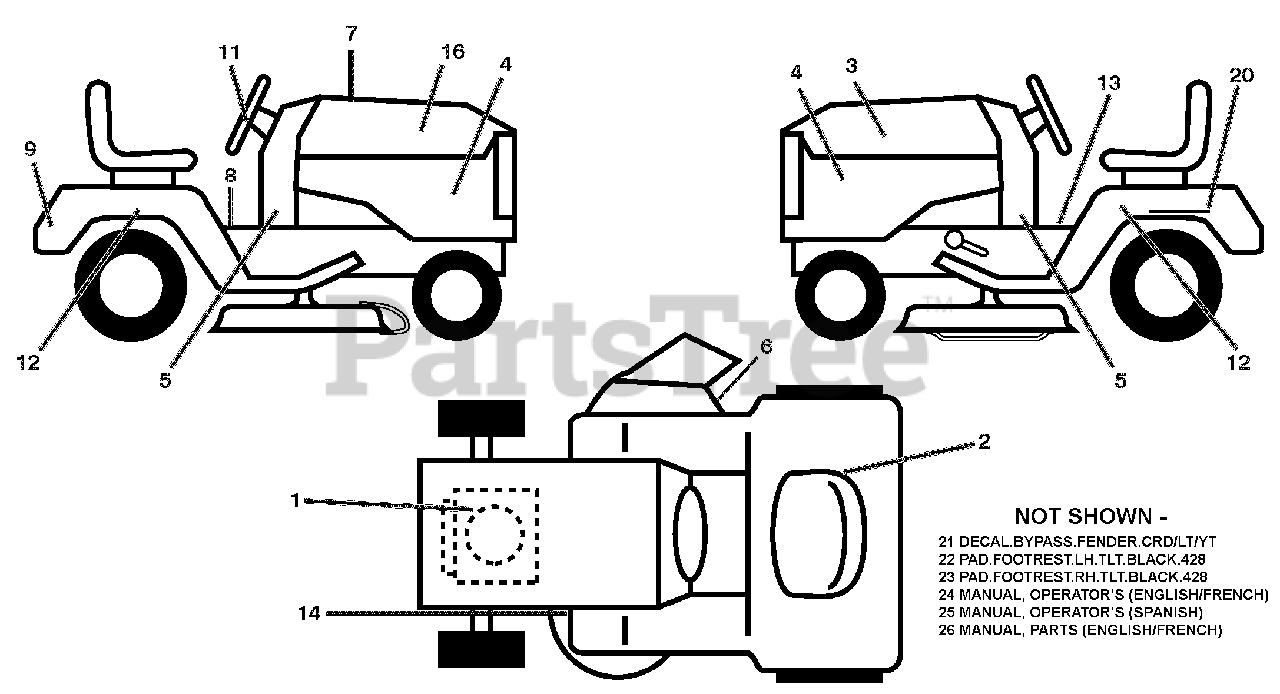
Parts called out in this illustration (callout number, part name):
1	DECAL ENGINE H.P.
2	Decal Fender Service
3	DECAL.HOOD.LH.3HIGH.ARIENS
4	Decal, Side Panel
5	DECAL.DASH.LWR.18HP.ARIENS
6	DECAL.MOWER.WARN.KEEP HAND AWY
7	DECAL.RPL.KH(SNGL).TLW.42.PMST
8	DECAL.FENDER.WARNING.ENG/FR.07
9	Decal, Fender
11	DECAL.WHEEL.STEER.ARIENS
12	DECAL.FENDER.SIDE.HYDRO.ARIENS
13	Decal, Flag
14	DECAL.V-BELT.SCH.42/46"MEC/ELE
16	DECAL.HOOD.RH.3HIGH.ARIENS
20	DECAL.BAT.DAN/POI P/L SYM.WPN
